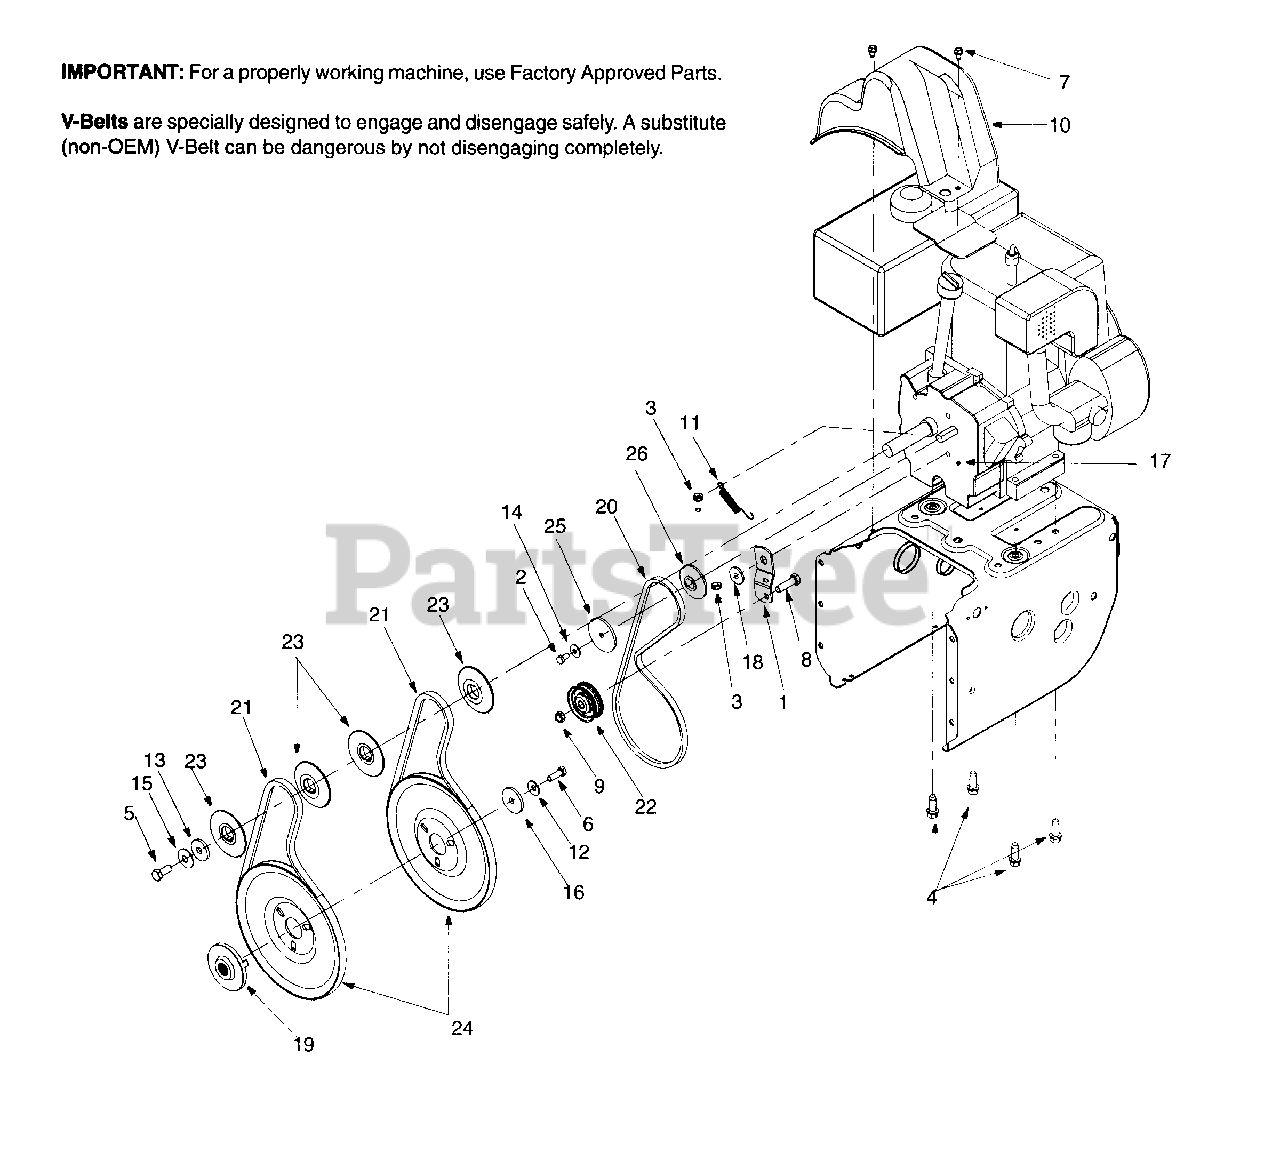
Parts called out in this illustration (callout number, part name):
3	Hex Screw w/Patch: 5/16-24 x 0.75"
4	Hex Washer Head TT Sems Screw
5	Hex Bolt 3/8-24 x .875" Gr8
6	Hex Screw w/Patch: 5/16-24 x .875" Gr.5
7	Hex Washer Head TT
8	Hex Screw: 3/8-16 x 1.0"
9	Top Lock Jam Nut: 3/8-16
10	Belt Cover
11	Extension Spring
12	Belleville Washer
13	Flat Washer
14	Bell Washer
15	Bell Washer
16	Flat Washer
17	Grease
18	Shoulder Spacer
19	Adapter Pulley
20	V-Belt
21	Belt
22	Flat Idler
23	Pulley Half
24	Auger Pulley
25	Pulley Half
26	Pulley Half
